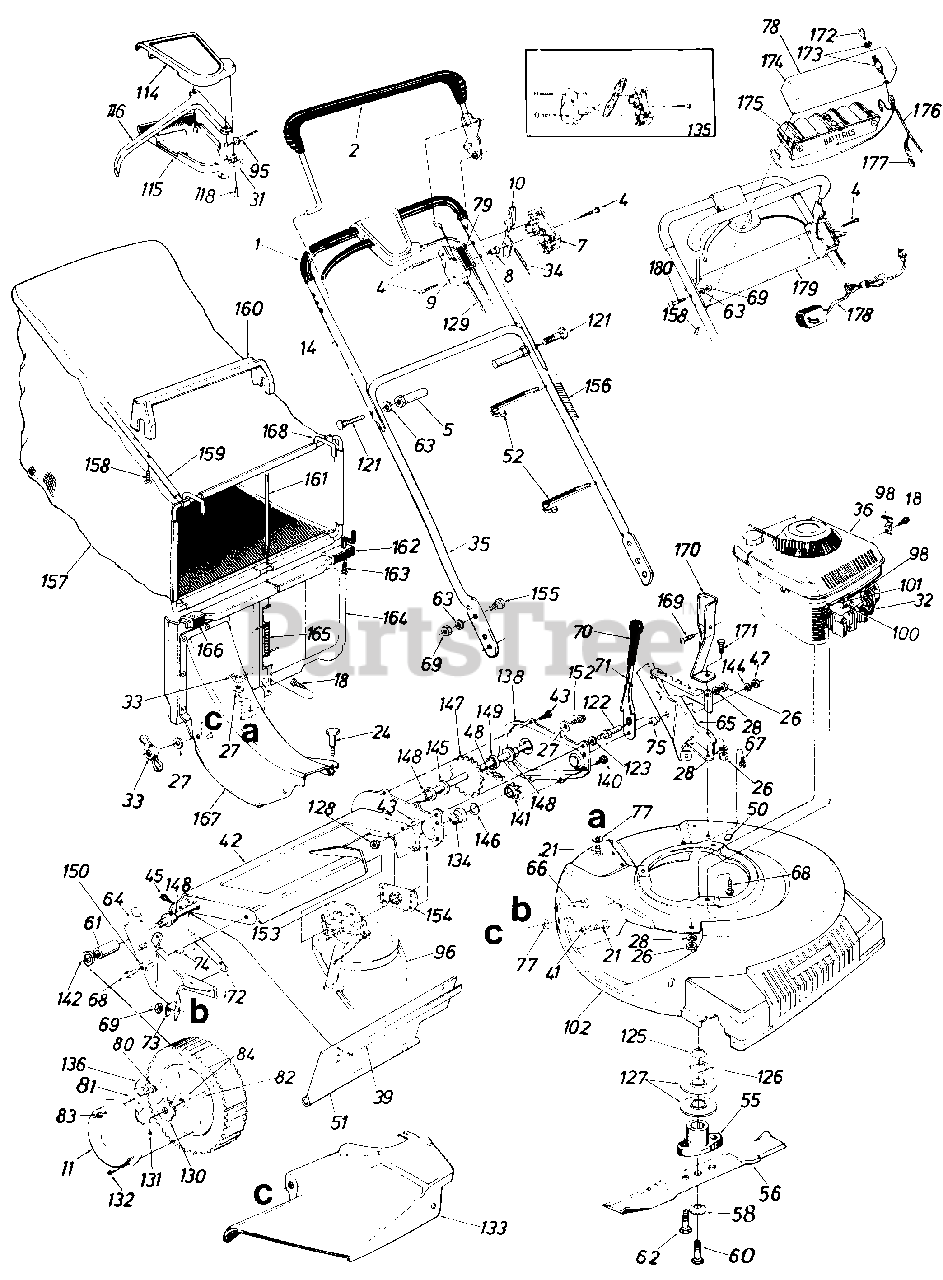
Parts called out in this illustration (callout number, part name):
2	Control Handle Ass'y. L.H.
4	Truss Mach. Scr. #12 x 1.50" Lg.
5	Catcher Support Pin
7	Control Panel Half
8	Control Disc Pin
9	Clutch Panel Half
10	Throttle Control Lever
11	Hub Cap
14	Upper Handle Chrome
18	Hex B-Tap Scr. #10 x .38"
21	Carriage Bolt 1/4-20 X .62"
24	Shoulder Bolt .312 Dia. x .18 Lg. Special
26	Hex Nut 1/4-20 Thd.
27	Bell-Wash. 1/4" I.D.
28	L-Wash. 1/4" I.D.
31	S.P. Control Cover
32	Spark Plug Insulator
33	Wing Nut
34	Throttle Control Wire 58"
35	Lower Handle Chrome
36	Engine
39	Retaining Strip
41	Fl-Wash. .344" I.D. x .62"
42	Chain Axle Ass'y.
43	Hex B-Tap Scr. 1/4" X .38"
45	Hex AB-Tap Scr. 1/4 X .62"
47	Hex Patch L-Nut 3/8-24 Thd.
48	#48 Chain .500" Pitch x .30 Links
51	Rear Flap 3.75" x 17.30" Lg.
52	Cable Tie
55	Blade Adapter
56	21" Blade
58	Bell-Wash. .460" I.D. x 1.38"
60	Hex Bolt 7/16-20 x 1.5
61	Spacer .513" I.D.
62	Hex L-Wash. Scr. 3/8-16 x . 75"
64	R.H. Handle Wheel Brkt. Ass'y.
65	L.H. Handle Wheel Brkt. Ass'y.
66	Carriage Bolt 5/16-18 x .62"
67	Hex Wash. Hd. B-Tap Scr. 5/16-18
68	Hex Wash. Hd. TT-Tap Scr. 3/8-16
69	Hex Nut 5/16-18 Thd.
71	Height Adj. Lever
72	Extension Spring 3.80" Lg.
73	Bell-Wash. 5/16" I.D.
74	Spacer.385" I.D.
75	Shld. Spacer.5" Dia.
77	Bolt Retainer 1/4 X .50" O.D.
78	Instruction Label
79	Control Label
80	Shld. Scr. .342" Dia. x .268
81	Pawl
82	Wheel Ass'y. Comp. Rear
83	Hex Ins. L-Nut 1/4-20 Thd.
84	Flange Ball Bearing 1/2" I.D.
95	S.P. Cable x 50" Lg.
96	"V"-Belt
98	Casing Clamp
100	Hex B-Tap Scr. #10 x .62"
101	Casing Clamp
115	Self-Propelled Control Cover
116	Control Lever
118	Fl-"C"-Sunk Hd. Tap Scr. #10 x .75" Lg.
121	Curved Carr. Bolt 5/16-18 x 1.75" Lg.
122	0287020002 Shld. Pin 1.43" Lg.
123	L-Wash. 3/8" I.D.
125	Serrated.Wash. 1.0" I.D.
126	Wave Wash. 1.005" I.D.
127	Serrated Pulley Half
128	Hex Nut 3/8-24 Thd.
129	Control Cable 46"
130	Ratchet Wheel 1.62" O.D.
131	Cotter Pin 1/8" Dia. x 1"
132	Pan Hd. Tap Scr. #12 x .50"
133	Side Chute Deflector Ass'y.
134	Flange Bearing
135	Kit Control Housing Comp.
136	Spring Nylon
138	Chain Cover
140	Hex Wash. S-Tap Scr. 1/4-20 x.50" Lg.
141	Sprocket Shaft Ass'y.
142	Fl-Wash. .510" I.D. x 1.0"
144	Fl-Wash. .385" I.D. x .87"
145	Fl-Wash. .51" I.D. x 1.0"
146	Fl-Wash. 3/8" I.D.
147	Rear Shaft Ass'y. 21.94" Lg.
148	Hex Flange Brg. .506" I.D.
149	Fl-Wash. .531" I.D. x .930"
150	Fl-Wash. 3/8" I.D.
152	Hex Bolt 1/4-20 x .62" Lg. (Grade 5)
153	Transmission Comp.
154	Hex Bearing Cup
155	Truss Mach. Scr. 5/16-18 x .75" Lg.
156	Plastic Tubing
157	Grass Bag
158	Truss Mach. B-Tap Scr. #12 x 1.5" Lg.
161	Chute Rod .188" Dia.
162	Door Clip
163	Hex AB-Tap Scr. 1/4 x .75" Lg.
164	Chute Door
165	Torsion Spring
166	Panel Clip
167	Top Discharge Chute Ass'y.
168	Front Catcher Frame
169	Truss Mach. Scr. 1/4-20 x .50" Lg.
170	Grass Catcher Bracket
171	Hex Bolt 1/4-20 x .50" Lg.
172	Ignition Key
173	Ignition Switch
174	Battery Tray
175	Battery Pack
176	Wire Harness
177	Plug
178	Battery Charger
179	Lower Battery Tray
180	Curved Carr. Bolt 5/16-18 x 1.38" Lg.
